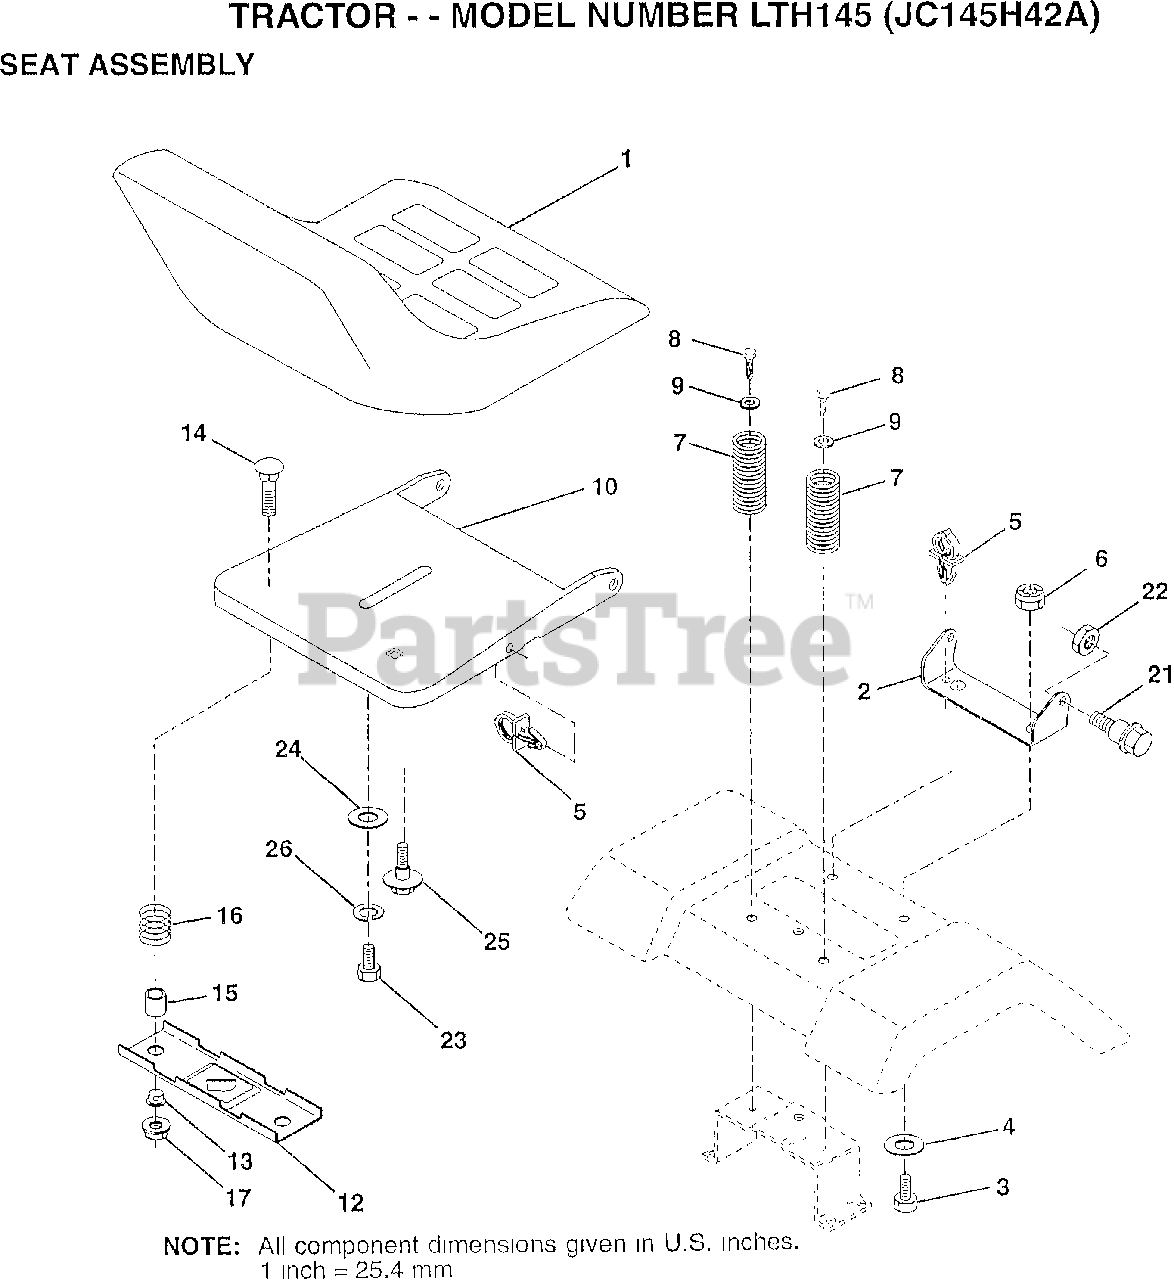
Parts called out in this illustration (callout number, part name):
3	BOLT FIN HEX 3/8-16 X 1
4	WASHER 13/32 X 1 X 10 GA
6	LOCKNUT
8	SCREW THDROL 3/8-16 X 1 TY-TT
9	WASHER 13/32 X 1 X 14 GA
14	BOLT RDHD SQNK 1/4-20X 1-3/8
22	LOCKNUT
23	BOLT FIN HEX 1/2-13 X 7/8 GR 5
24	WASHER 17/32 X 1-3/16 X 12 GA
26	WASHER LOCK HVY HLCL SPR 1/2
